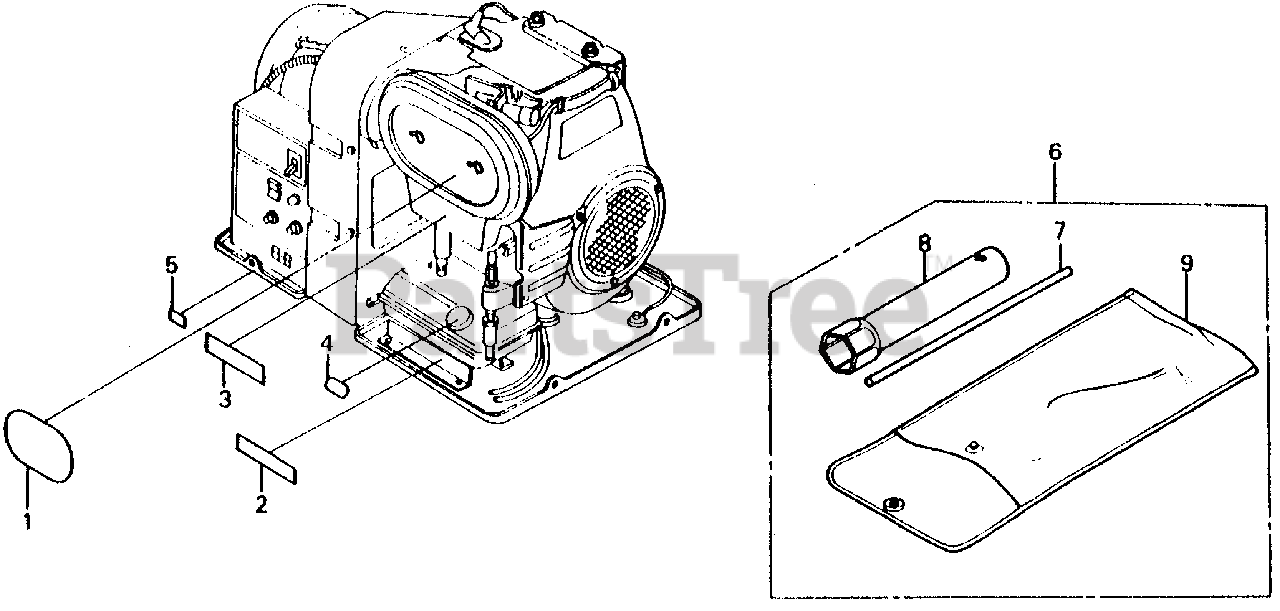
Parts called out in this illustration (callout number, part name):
1	MARK, AIR CLEANER COVER (NOT AVAILABLE)
2	MARK, CAUTION
3	MARK, INTERVAL (NOT AVAILABLE)
4	MARK, OIL CAUTION
5	MARK (NEGATIVE)
6	TOOL KIT (N/A: SEE COMPONENTS)
7	BAR, PLUG WRENCH
8	WRENCH, BOX (P21)
